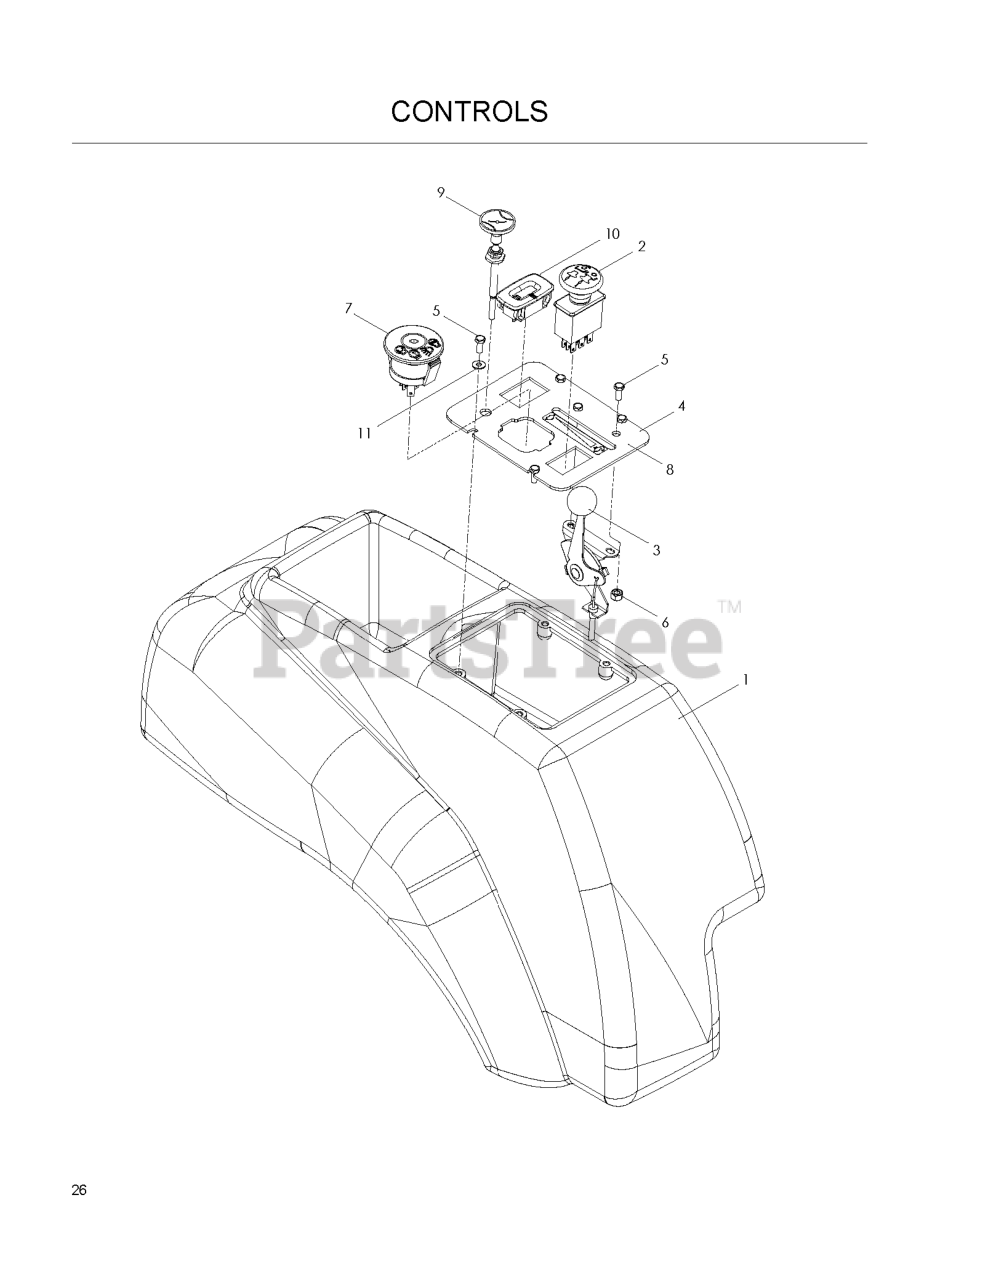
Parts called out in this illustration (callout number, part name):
1	FENDER CONSOLE
1	WASHER #10
1	HOUR METER
2	RP.SWITCH, BLADE
3	THROTTLE CABLE
4	CONSOLE PLATE, BLACK
5	HCS #10-24 X 1/2
6	NUT 10-24 NYLOC
7	RP IGNITION SWITCH
8	DECAL, THROTTLE
9	CHOKE CONTROL
